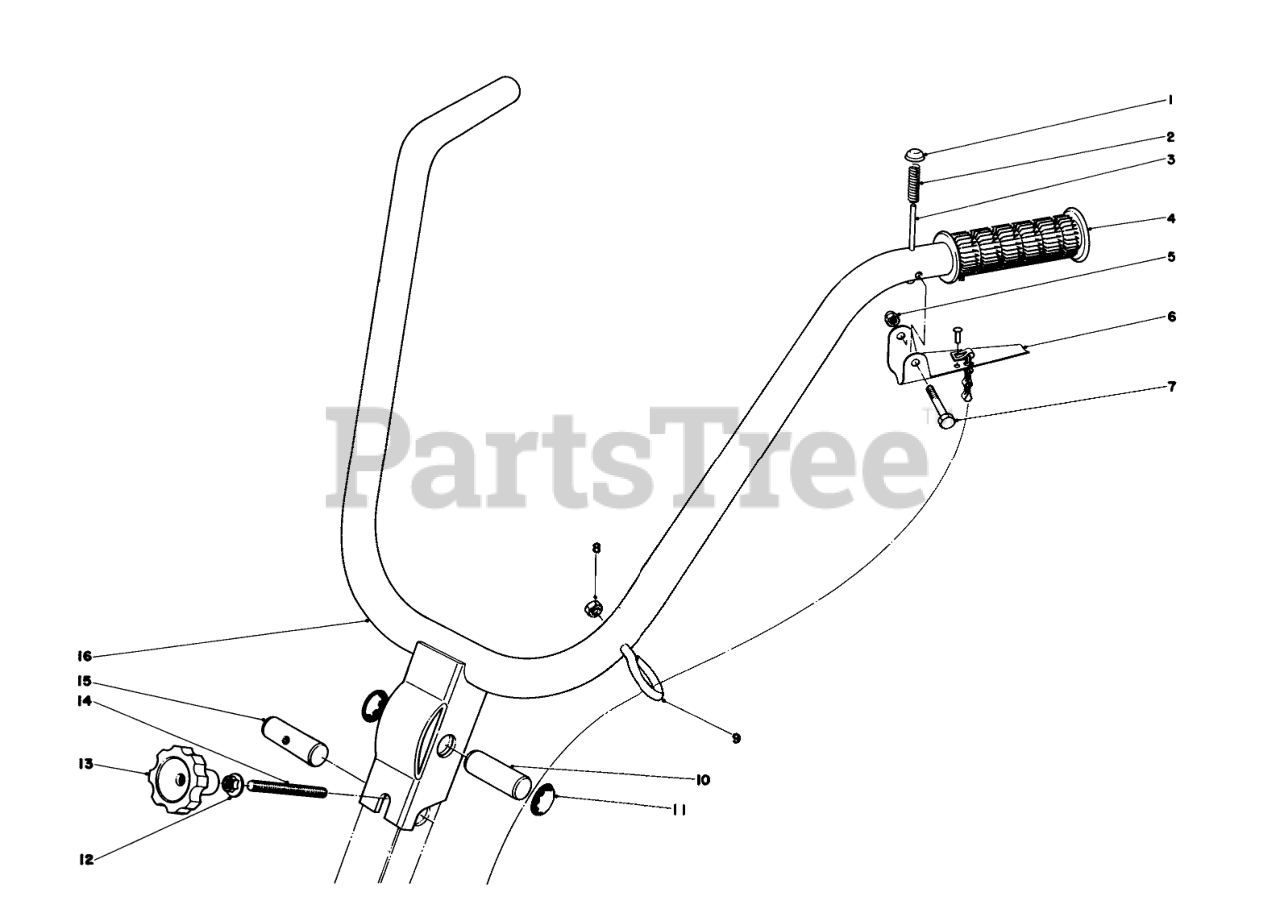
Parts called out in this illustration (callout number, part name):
1	Push-On
2	Spring
3	LOCK PIN
4	GRIP-HANDLE
5	NUT-CAP
6	Lift Bail Chain Assembly
7	Hex. Hd. Capscrew
8	NUT-HEX, SIDE DEFORM
9	Eye Bolt
10	PIVOT PIN
11	PUSH-ON
12	NUT-FLANGE
15	Pin Handle
16	HANDLE BAR WA
